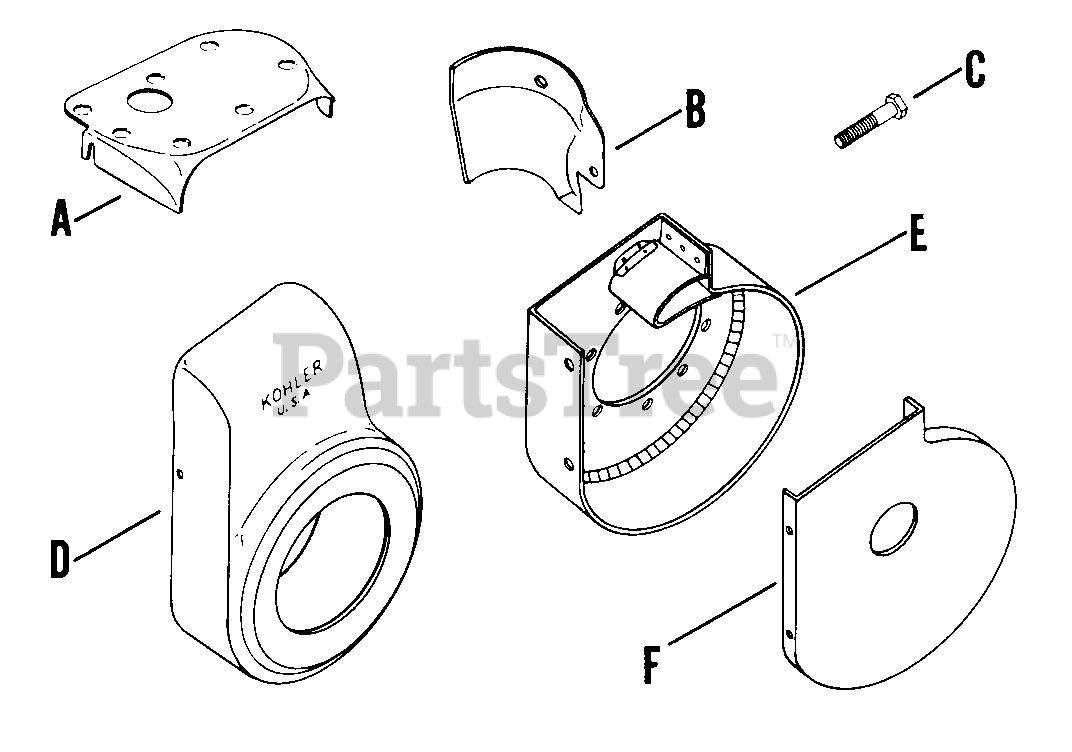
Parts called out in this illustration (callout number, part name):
A	BAFFLE, HEAD - (#DSC)
B	BAFFLE - DISCONTINUED
D	KIT, BLOWER HOUSING (#DSC)
